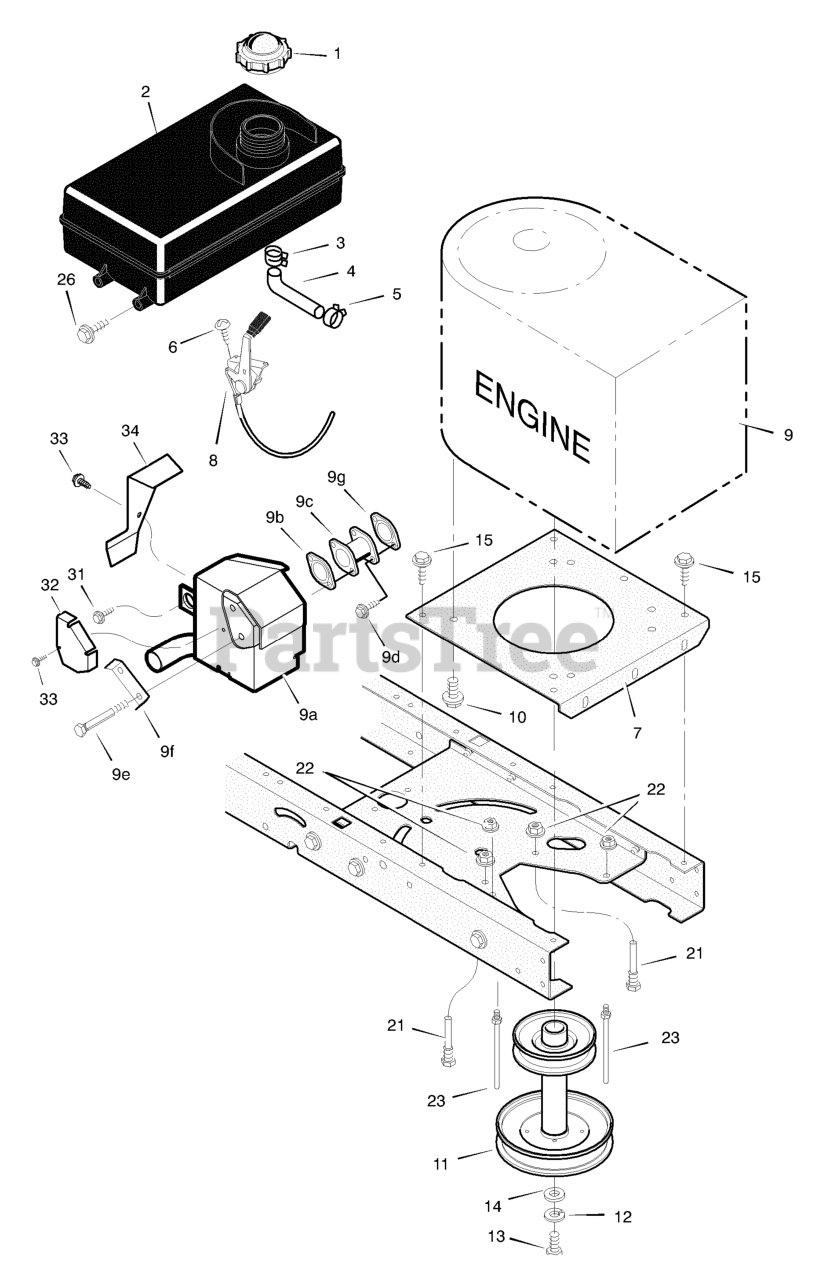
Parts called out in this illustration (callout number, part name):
1	Fuel Cap
2	TANK, Fuel 1.4 Gal.
3	Hose Clamp
4	Fuel Line (Must cut to length)
5	Hose Clamp
7	Plate, Engine
8	Throttle Control
9	Engine
9A	Muffler and Heat Shield
9B	GASKET, Exhaust
9C	Adapter, Muffler
9D	Screw, Adapter
9E	Bolt, Muffler
9F	Lock, Screw
9G	Gasket, Muffler
10	Bolt, Engine Mount
11	STACK PULLEY ASSEMBLY
12	Lockwasher
13	Bolt, Hex
21	Guide, Belt
22	Nut, Flange
23	Guide, Belt
32	Cover, Heat Shield
34	Cover Top Heat Shield
